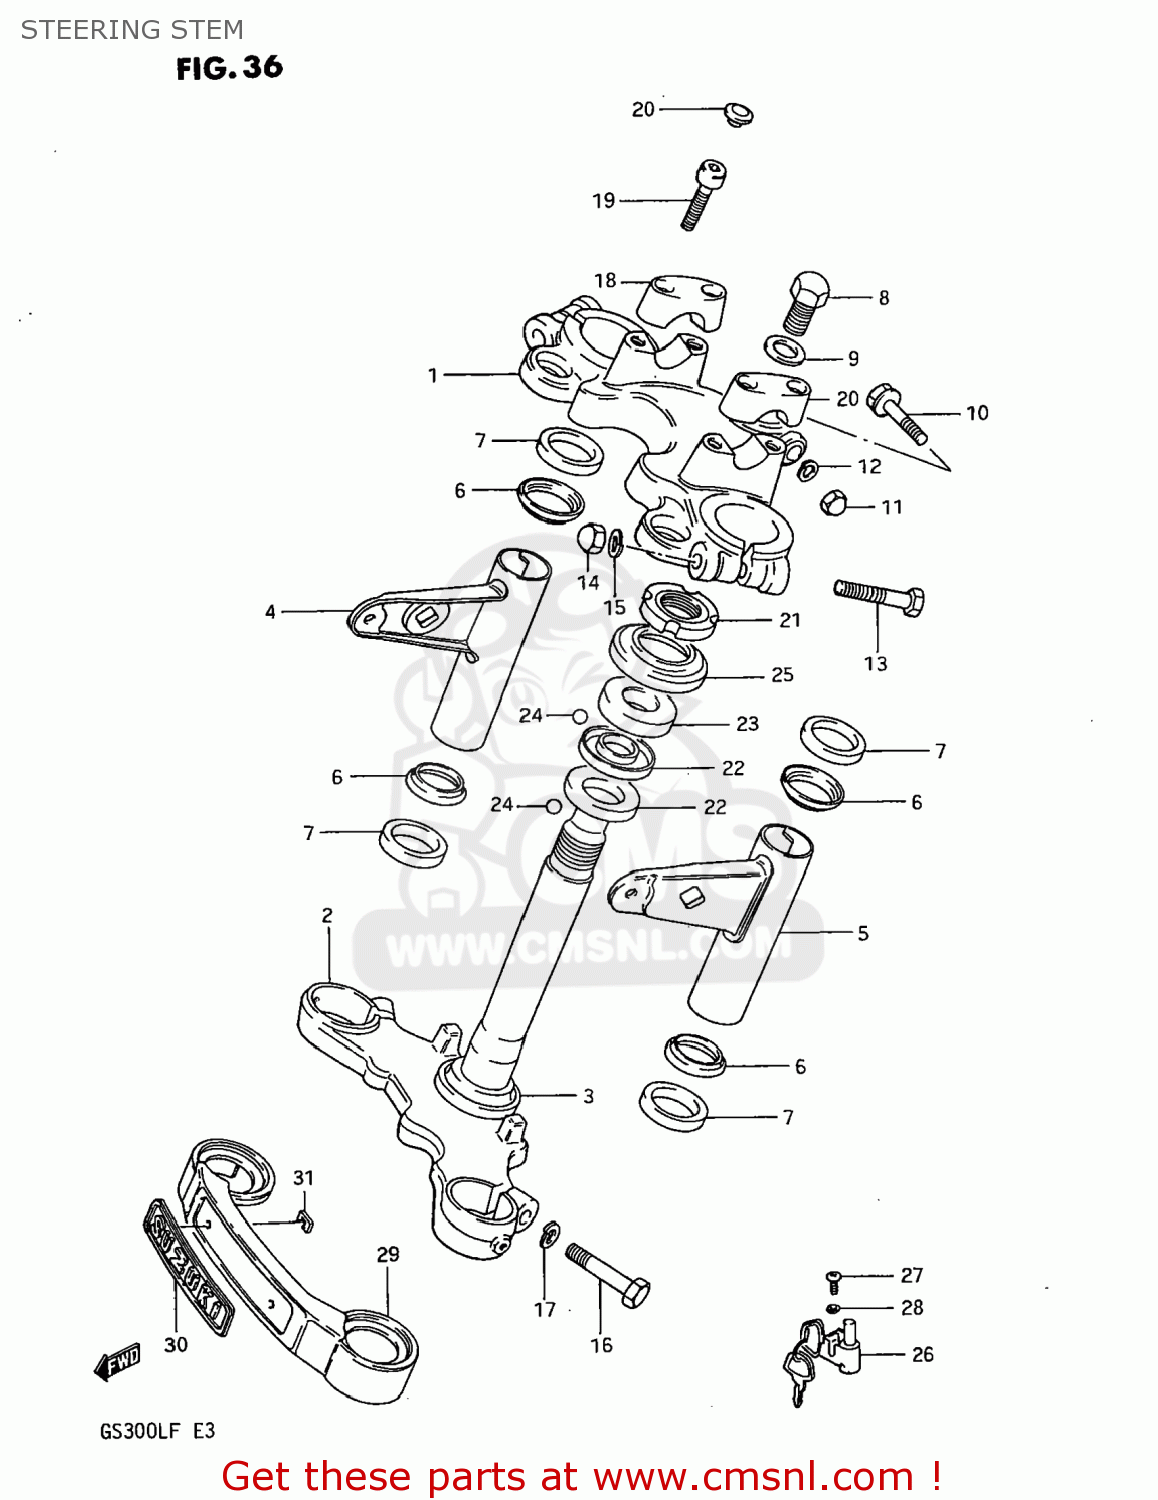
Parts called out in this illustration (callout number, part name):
1	HEAD,STEERING STEM
2	STEM,STEERING
3	RACE,STEERING OUTER LWR
4	BRACKET,HEADLAMP,RIGHT
5	BRACKET,HEADLAMP,LEFT
6	CAP,HEADLAMP BRACKET
7	CUSHION,HEADLAMP BRACKET
8	BOLT(12X20)
9	WASHER (12.5X27X1.6)
10	BOLT, UPPER
11	NUT,M8X1.25X12
12	WASHER,LOCK,8.
13	BOLT
14	NUT
15	LOCK WASHER
16	BOLT
17	LOCK WASHER
18	HOLDER,HANDLEBAR(BLACK)
19	BOLT, REAR (8X30)
20	CAP(OD:14.5)
21	NUT,STEERING STEM(25X44X10)
22	LACE,STEERING INNER LWR
23	LACE,STEERING OUTER UPR
24	BALL
25	DUST SEAL,STEERING UPR
26	LOCK ASSY,STEERING
27	SCREW
28	LOCK WASHER
29	COVER,FRONT FORK
30	EMBLEM,FR FORK COVER
31	NUT
